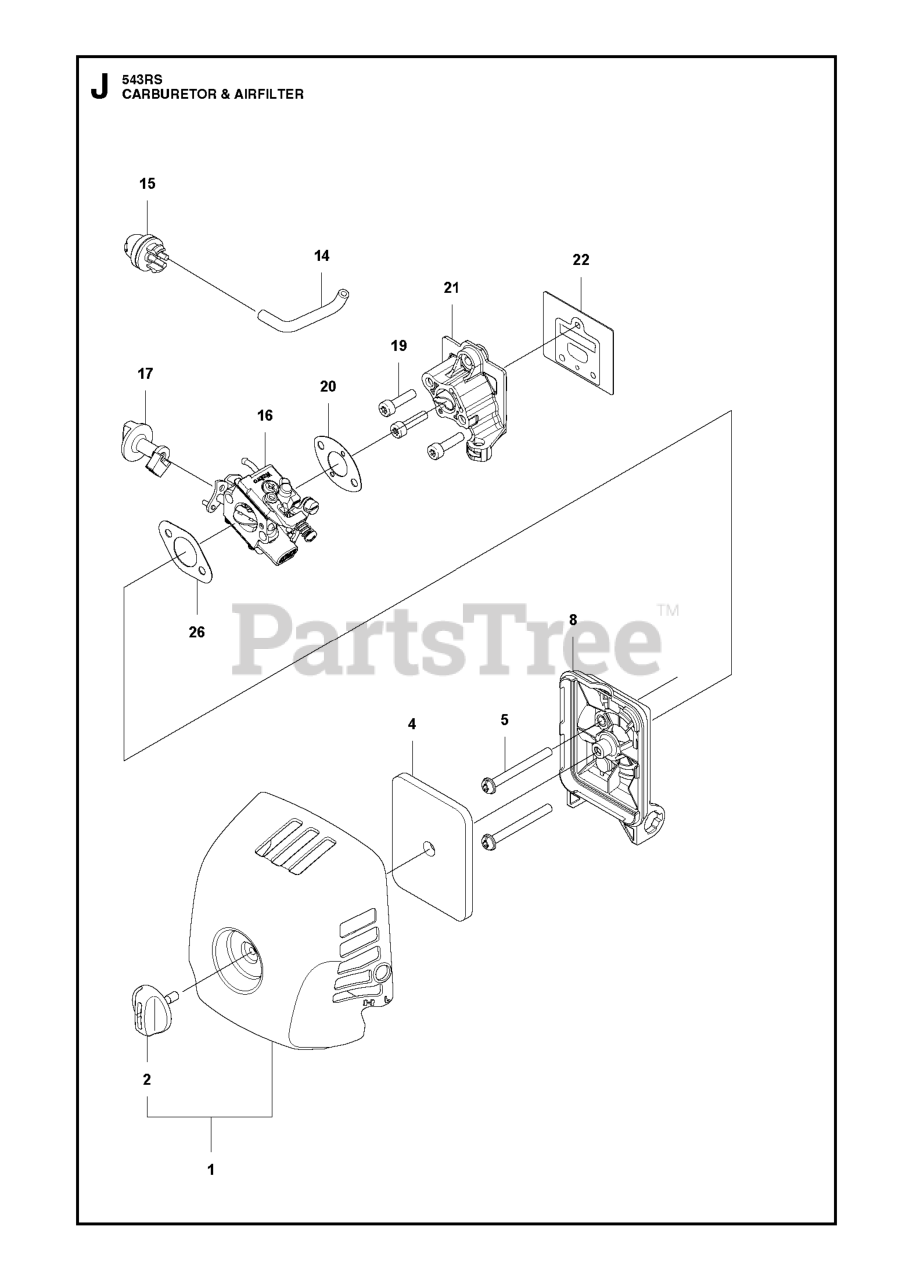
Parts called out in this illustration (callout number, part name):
2	TURNING KNOB GZ40N7
15	PRIMARY BTN
16	Carburetors
22	GASKET, INSULATOR
